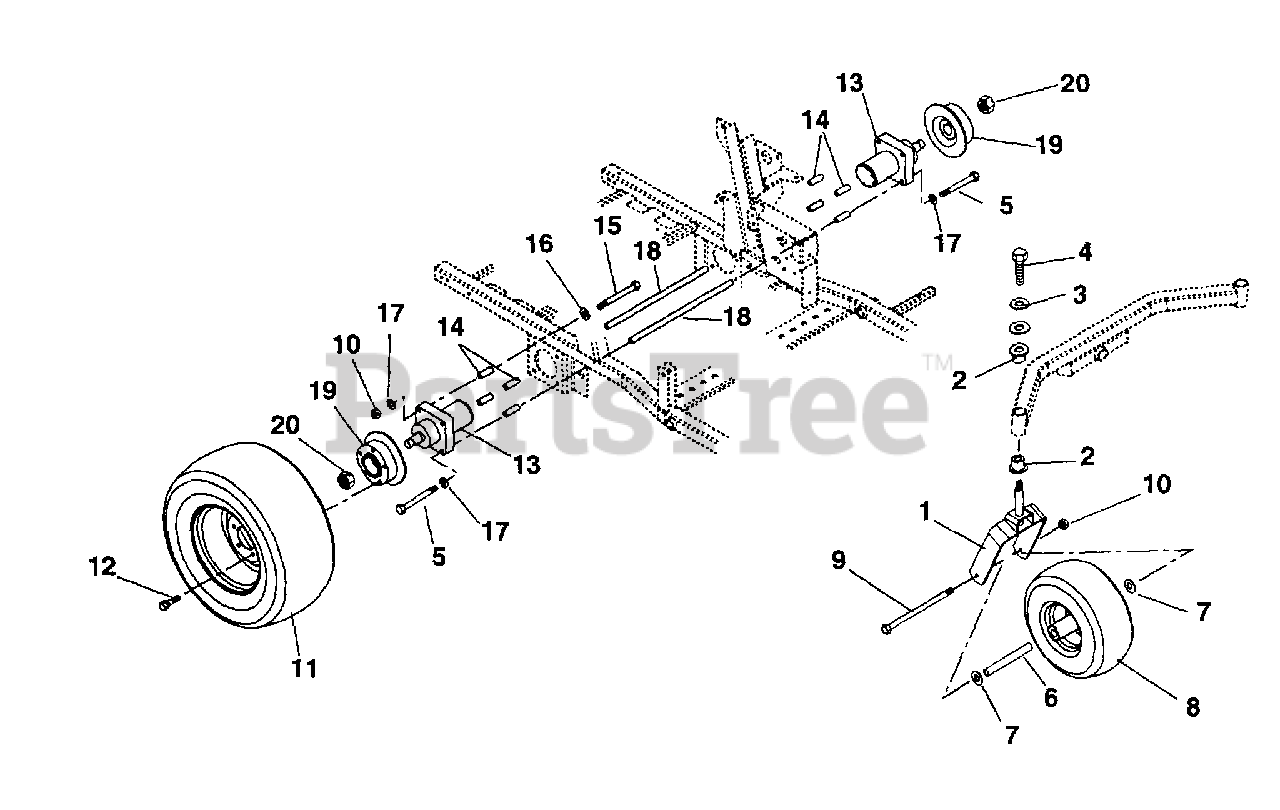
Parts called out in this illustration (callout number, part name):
1	WMT, FRONT FORK - ORANGE
2	BSHG-FLG1.020X1.385X.75X1.75NY
3	WSHR-FL-STL .380X1.50X.125YWZC
4	@WSHR-LK .38X.094 REG YWZC
5	@BLT-HEX .38-16X1.25 GR5 YWZC
6	SPACER - WHEEL
7	WSHR-FL-STL .515X1.625X.250 YZ
8	WHEEL/TIRE ASM
9	@BLT-HEX .50-13X9.00 GR5 YWZC
10	@NUT-LK-CTR .50-13 YWZC
11	WHL/TIRE 23X8.50-12 MULTITRAC
12	BLT-LUG .50-20X.75X1.62 PL
13	HYDRAULIC WHEEL MOTOR
14	BSHG-SLV .513X.748X2.129
15	@BLT-HEX .50-13X5.00 GR8 YWZC
16	BSHG, SPCR.500X.750X.321 PM
17	@WSHR-LK .50X.125 REG YWZC
18	ROD-MOTOR CONNECTING
19	HUB & DISK (PARK) 8" 1/2 HOLE
20	NUT-LK-JAM-PTCH 1.00-20
